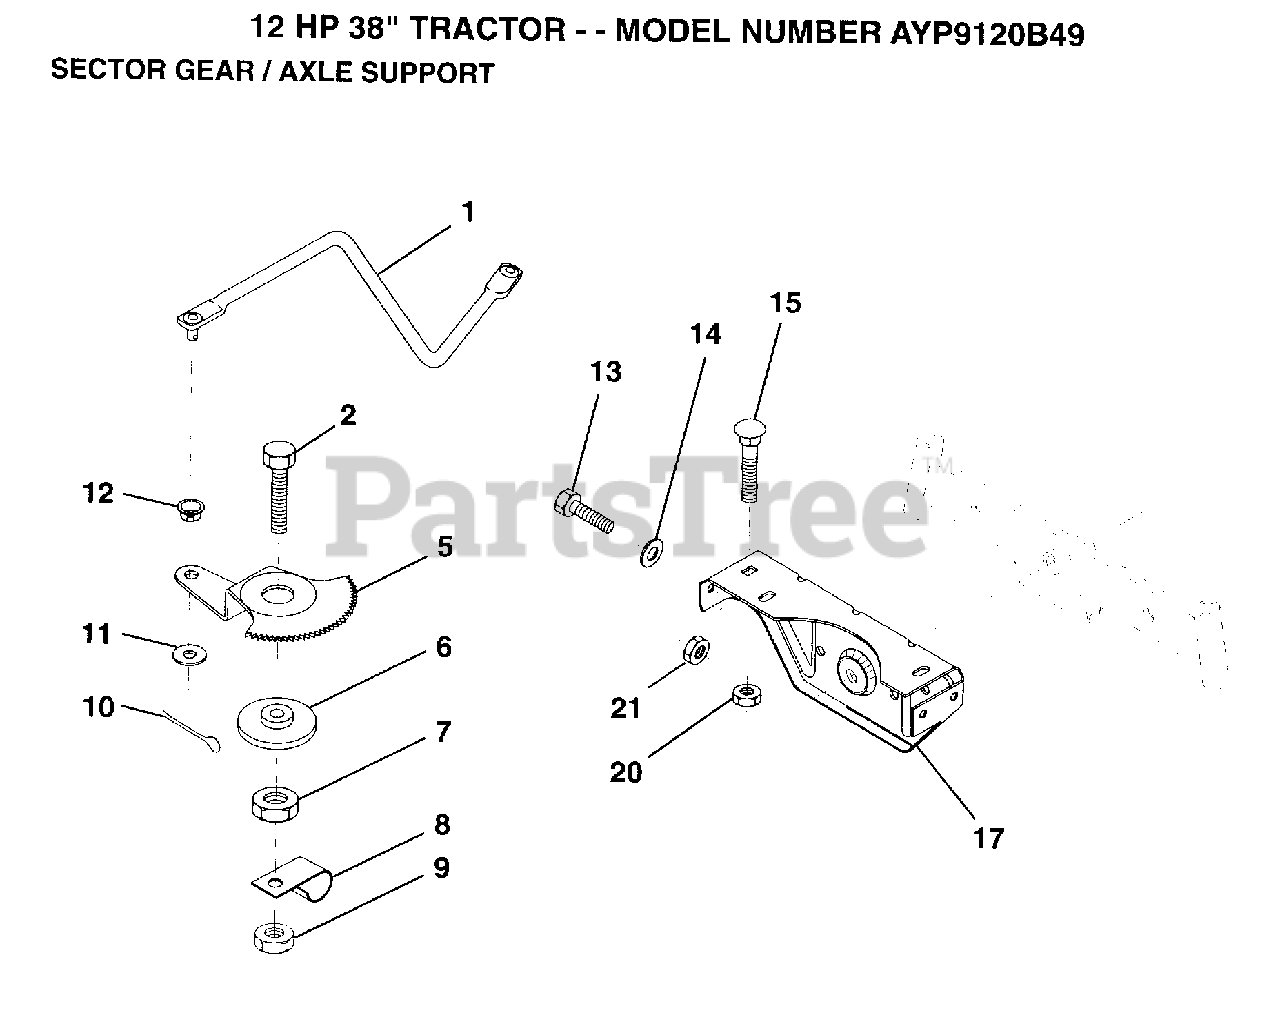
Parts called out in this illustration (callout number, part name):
1	DRAG LINK
2	"BOLT,HEX"
5	GEAR SECTOR
6	BUSHING
7	NUT
8	CLIP INSULATOR
9	NUT LTV
10	COTTER PIN
11	WASHER
12	BUSHING.DRAGLINK
13	BOLT
14	WASHER
15	BOLT
17	SUPT AXLE FRONT
20	NUT
21	NUT
